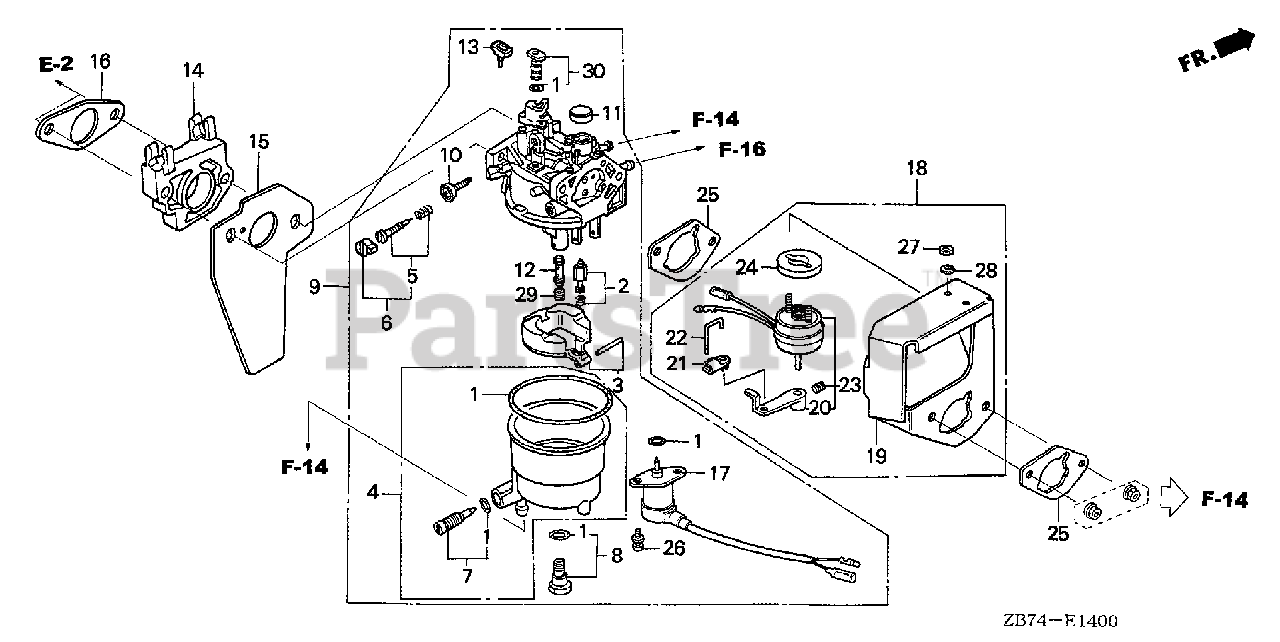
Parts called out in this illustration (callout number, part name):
1	GASKET SET
2	VALVE SET, FLOAT
4	CHAMBER SET, FLOAT
5	SCREW SET, PILOT
7	SCREW SET, DRAIN
9	CARBURETOR ASSY. (BE22C C)
10	SCREW, THROTTLE STOP
11	CAP, CHOKE DUST
12	NOZZLE, MAIN
14	INSULATOR, CARBURETOR
15	GASKET, CARBURETOR
16	GASKET, INSULATOR
17	VALVE ASSY., SOLENOID
18	STAY ASSY., SOLENOID
19	STAY, CHOKE SOLENOID
20	LEVER, CHOKE SOLENOID
21	JOINT, ROD
22	ROD, CHOKE SOLENOID
23	SOLENOID ASSY., CHOKE
24	SPACER, CHOKE SOLENOID
25	GASKET, AIR CLEANER
26	SCREW-WASHER (5X12)
27	NUT, HEX. (3MM)
28	WASHER, SPRING (3MM)
29	JET, MAIN (#78)
29	JET, MAIN (#80)
29	JET, MAIN (#82)
30	JET SET, PILOT (#40)
